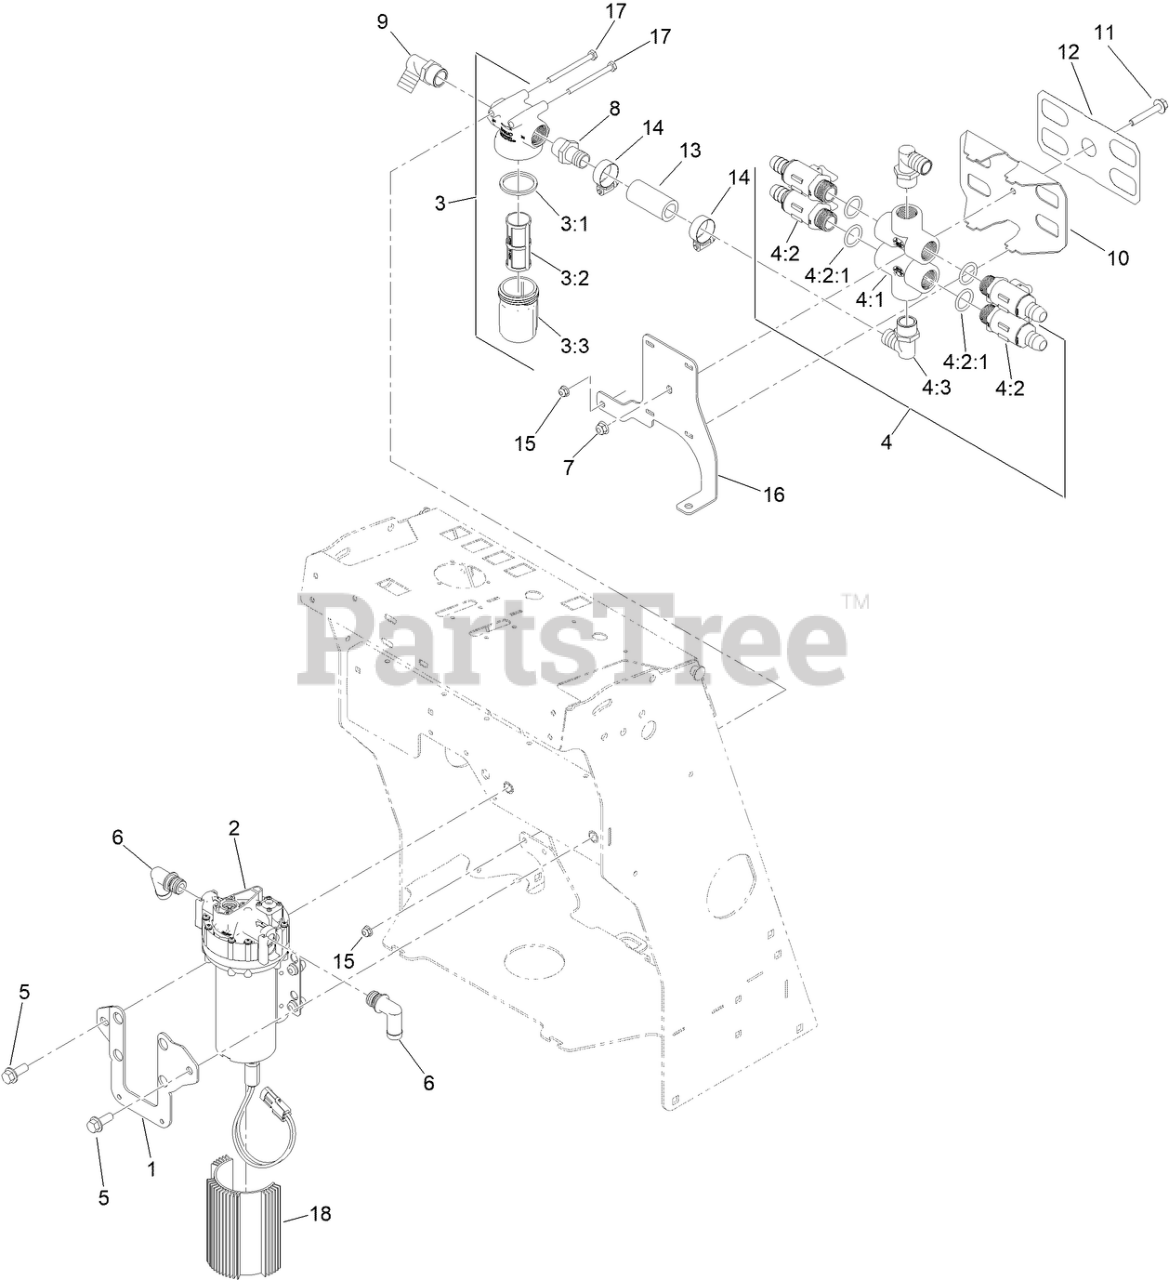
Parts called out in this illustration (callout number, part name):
1	BRACKET-MOUNT, PUMP
2	PUMP-5.3 GPM
3	STRAINER-T, 50 MESH
3:1	Gasket-Strainer
3:2	SCREEN-50 MESH
3:3	BOWL-STRAINER, BLACK
4	ASM-VALVE, SELECTOR
4:1	FITTING-TEE
4:2:1	O-RING, -213
4:3	FITTING-ELBOW, 90
5	SCREW-HHF
6	FITTING-ELBOW
7	Nut-Hex Flange
8	HOSEBARB
9	FITTING-ELBOW, 90
10	BRACKET-VALVE, SELECTOR
11	SCREW-HHF
12	DECAL-VALVE
13	HOSE-SPRAY
14	CLAMP-HOSE
15	Nut-Hex Flange
16	PLATE-VALVE, MOUNT
17	HHCS,1/4-20X3,ST/ST,18-8
18	HEATSINK-3.0""
